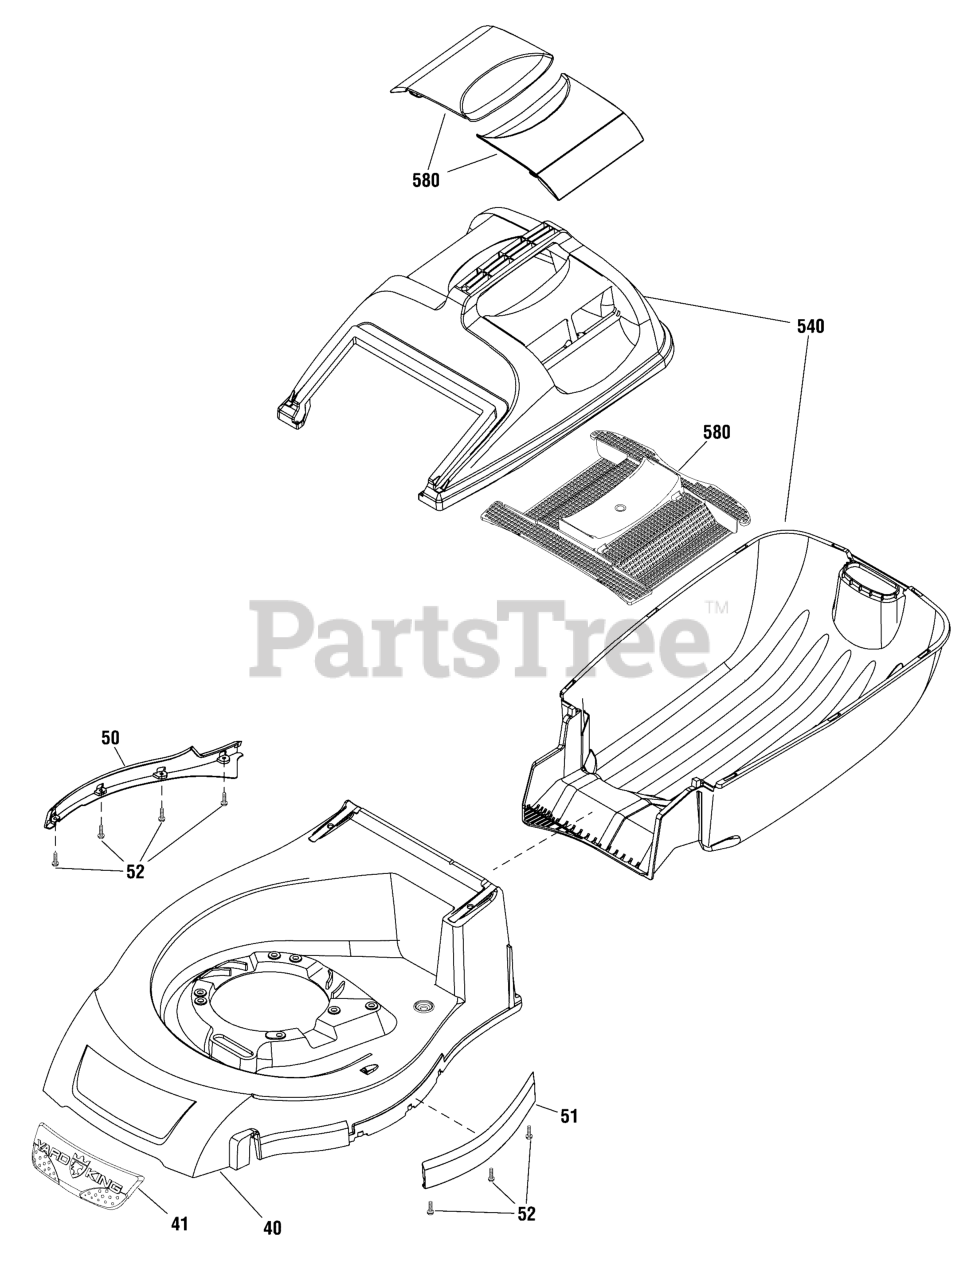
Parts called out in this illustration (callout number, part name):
40	* BASEPLATE, Signal Red
40	BASEPLATE, Blue
41	BADGE, Yard King
50	SIDE TRIM, RH
51	SIDE TRIM, LH
52	SCREW, Side Trim
540	CATCHER ASSEMBLY
580	MESH & VENT PACK
